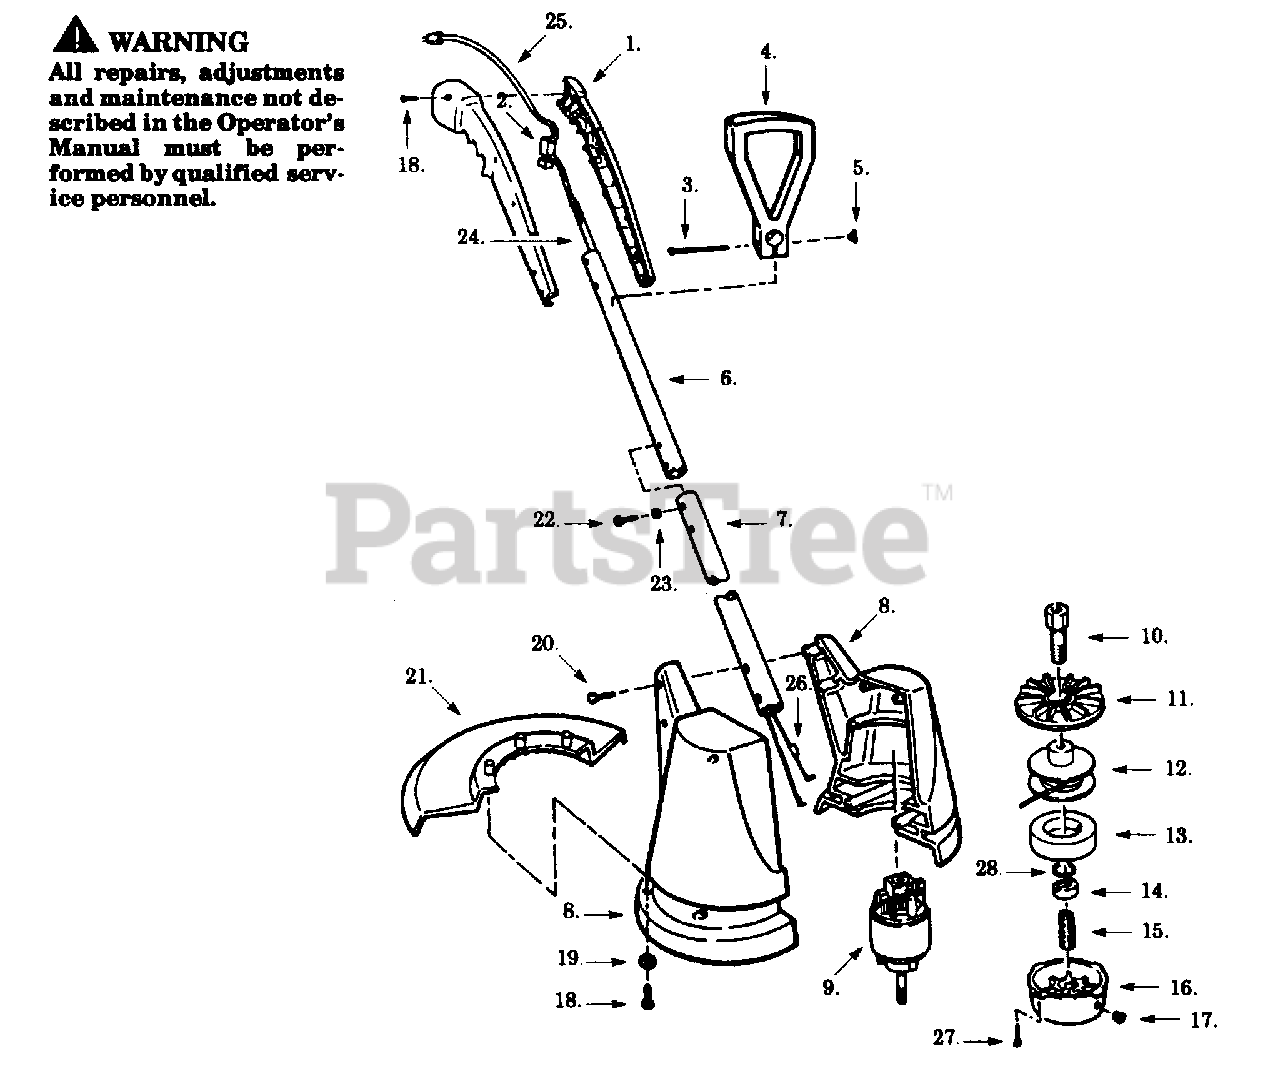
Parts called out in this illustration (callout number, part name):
1	R.H./L.H. Handle
2	Trigger Switch
4	Side Handle
5	Wing Nut
6	Upper Handle Tube
7	Lower Handle Tube
8	R.H./L.H. Housing
10	Drive Adapter
11	Rear Plate
12	Spool & Line
13	Foam Pad
14	Drive Adapter Nut
21	Line Cutter Guard
23	Lockwasher
25	Power Cord
26	Rectifier
27	Cotter Pin
